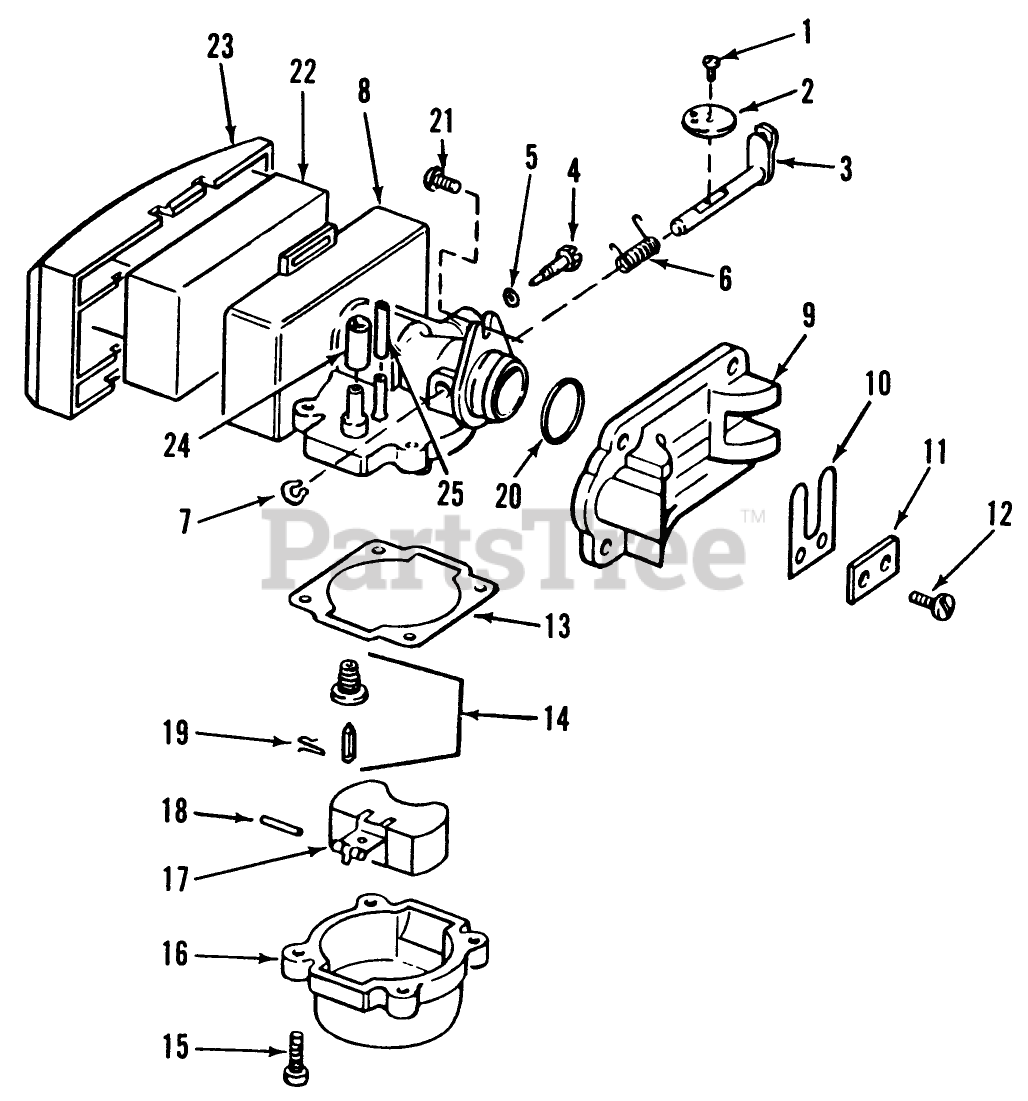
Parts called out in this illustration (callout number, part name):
1	SCREW F
2	THROTTLE DISC S
4	SCREW CARB ADJ S
7	RING GRIP S
8	CARB BODY AY S
11	PLATE-BACKUP, REED
13	GASKET S
15	SCREW-HH
21	SCREW
22	AIR FILTER S
23	COVER FILTER
23	COVER FILTER S
24	Gas line
